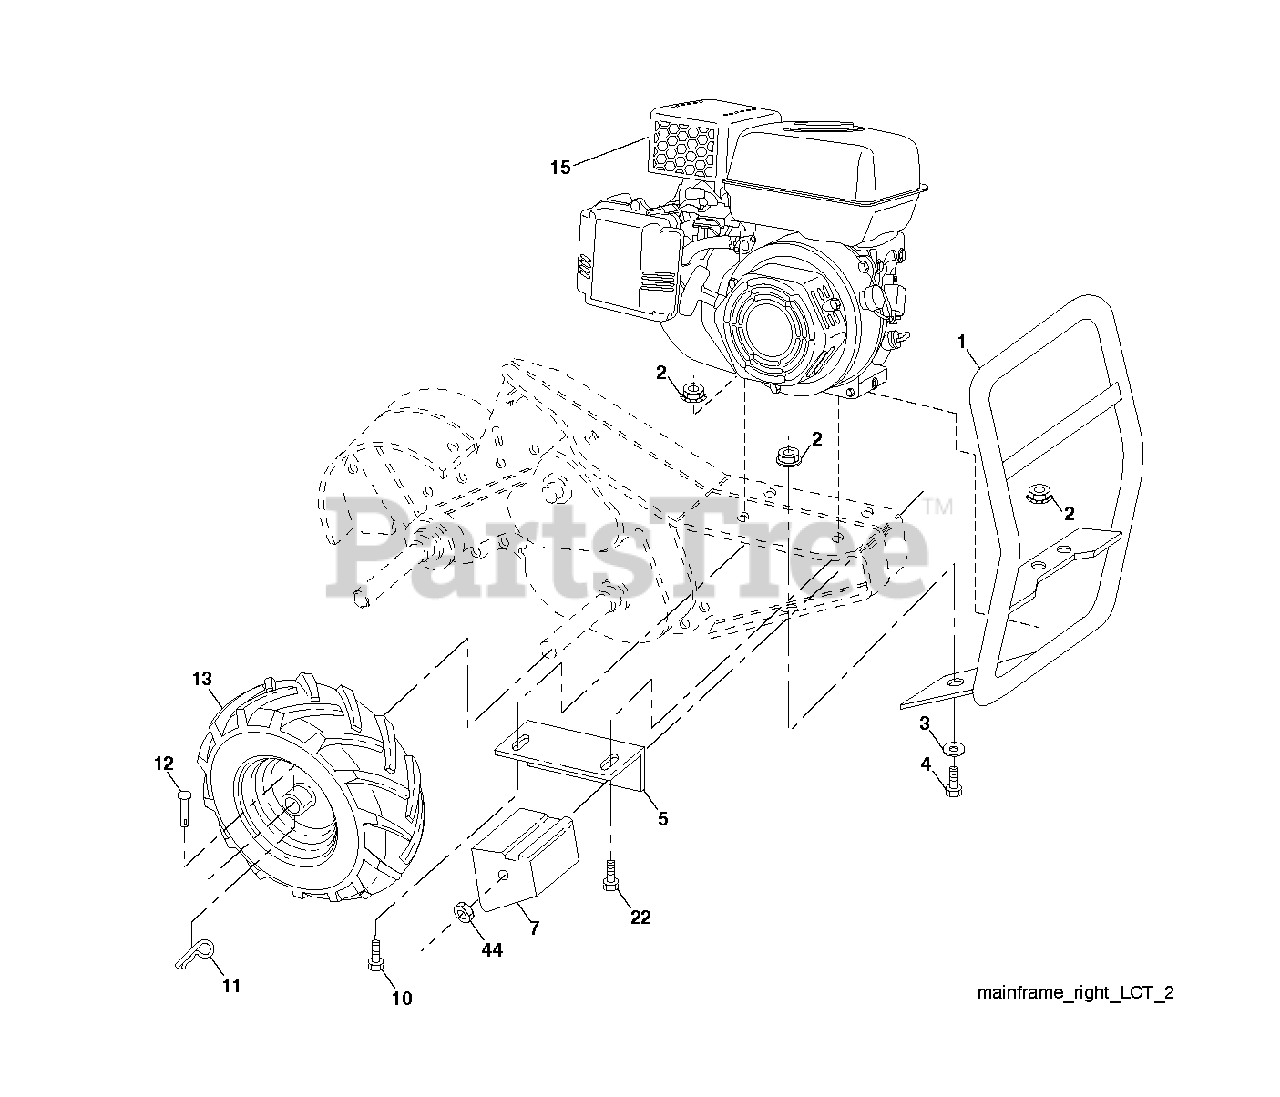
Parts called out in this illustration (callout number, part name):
1	RP.BUMPER.ASM.TILLER.
2	LOCKNUT-FLANGE 5/16-18
3	WASHER
4	BOLT
5	BRACKET RH CRT
7	COUNTERWEIGHT, RH
10	BOLT
12	RIVET,DRILLED
13	TIRE.16X4-8.CHEVRON.TILLER
15	Poulan TBD
22	BOLT, HEX 5/16-18X1-3/4
44	BOLT, HEX 5/16-18X1-3/4
